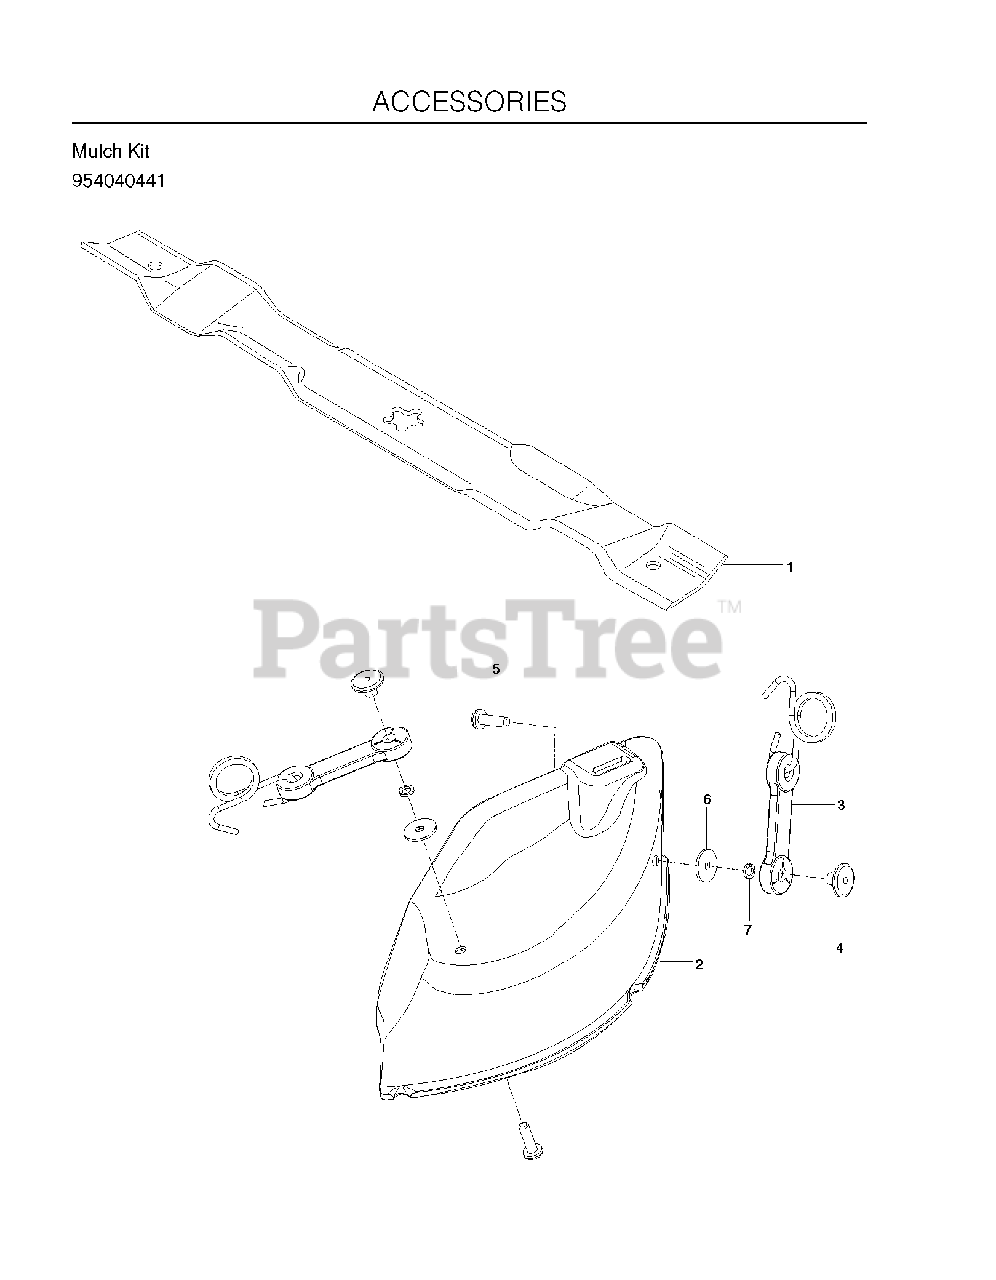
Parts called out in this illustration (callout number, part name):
1	BLADE 42" MULCHING STD
3	LATCH ASSY
5	SCREW #10-24 X 5/8
7	WASHER - 3/8
